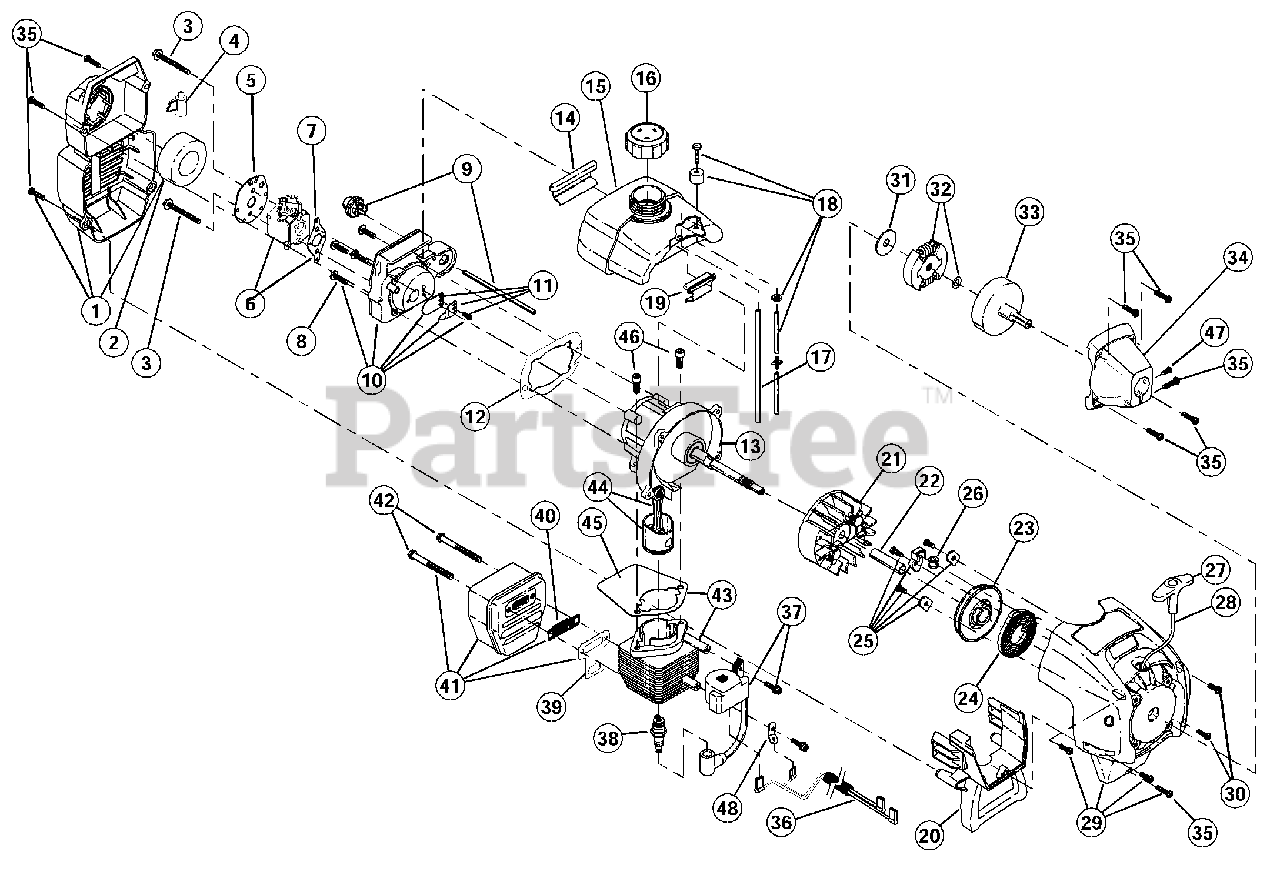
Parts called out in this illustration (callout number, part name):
1	Carburetor/Air Cleaner Cover Assembly
2	Air Cleaner Filter
3	Carburetor Mounting Screw Assembly
4	Choke Lever
5	Plate
6	Carburetor Assembly
7	Carburetor Gasket
8	Carb Mount Screw
9	Primer and Hose Assembly
10	Carb Mount Assembly
11	Reed Assembly
12	Carburetor Mount Gasket
13	Crank Case Service Assembly
14	Rear Mounting Pad
15	Fuel Tank Assembly
16	Fuel Cap Assembly
17	Fuel Return Line
18	Fuel Line Assembly
19	Front Mounting Pad
20	Shroud Extension and Stand
21	Flywheel Assembly
23	Recoil Pulley Assembly
24	Recoil Spring
25	Pulley Retainer Assembly
26	Rope Guide
27	Pull Handle
29	Starter Housing Assembly
30	Housing Screws
31	Clutch Washer
32	Clutch Rotor Assembly
33	Clutch Drum Assembly
34	Clutch Cover Assembly
35	Cover Screw
36	Wire Lead
37	Module Assembly
38	Spark Plug
39	Exhaust Gasket
40	Spark Arrestor
41	Muffler Assembly
42	Muffler Mounting Bolt Assembly
43	Cylinder Assembly
44	Piston and Rod Assembly
45	Cylinder Gasket
46	Cylinder Bolt
47	Anti-Rotation Screw
48	Ground Tab
